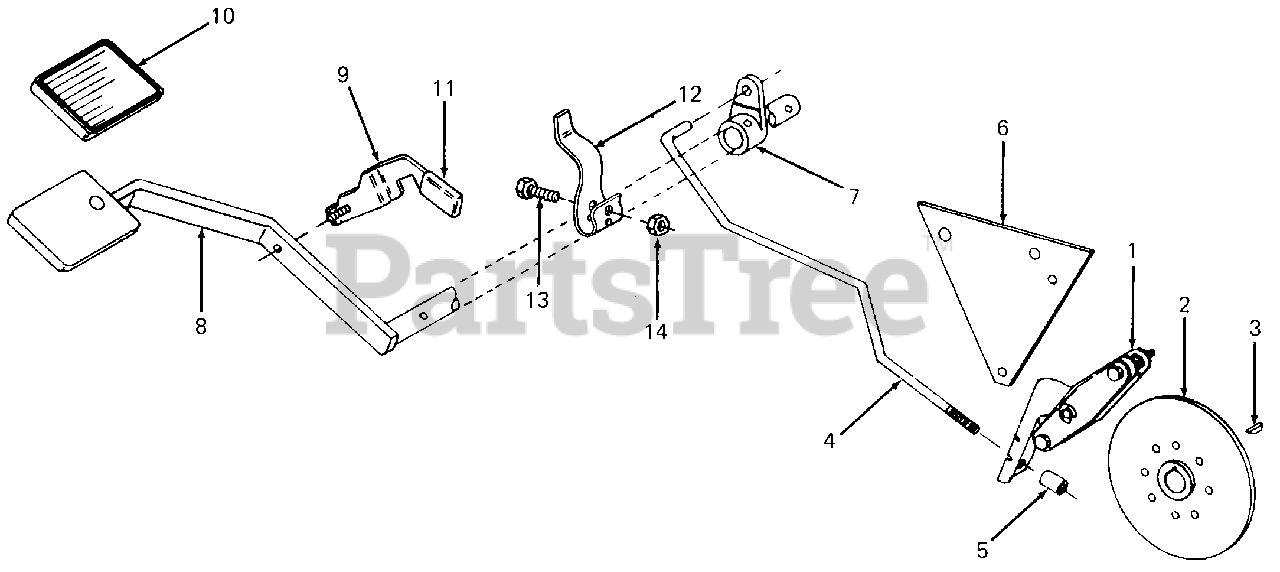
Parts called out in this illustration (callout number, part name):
1	Brake Assy, Caliper
2	Disc, Brake
3	Key, Woodruff #9, 3/16 X 3/4 Lg
4	Rod, Brake
5	Spacer, .375 X .465 X 1.0 Lg
6	Plate, Brake Spacer
8	Pedal Assy, Clutch
10	Pad, Pedal
11	Grip, Parking Brake
12	Spring, Switch Operating
13	Screw, Hex Cap, 1/4-20 X .75 Lg GR5
14	Nut, Hex Center Lock, 1/4-20
